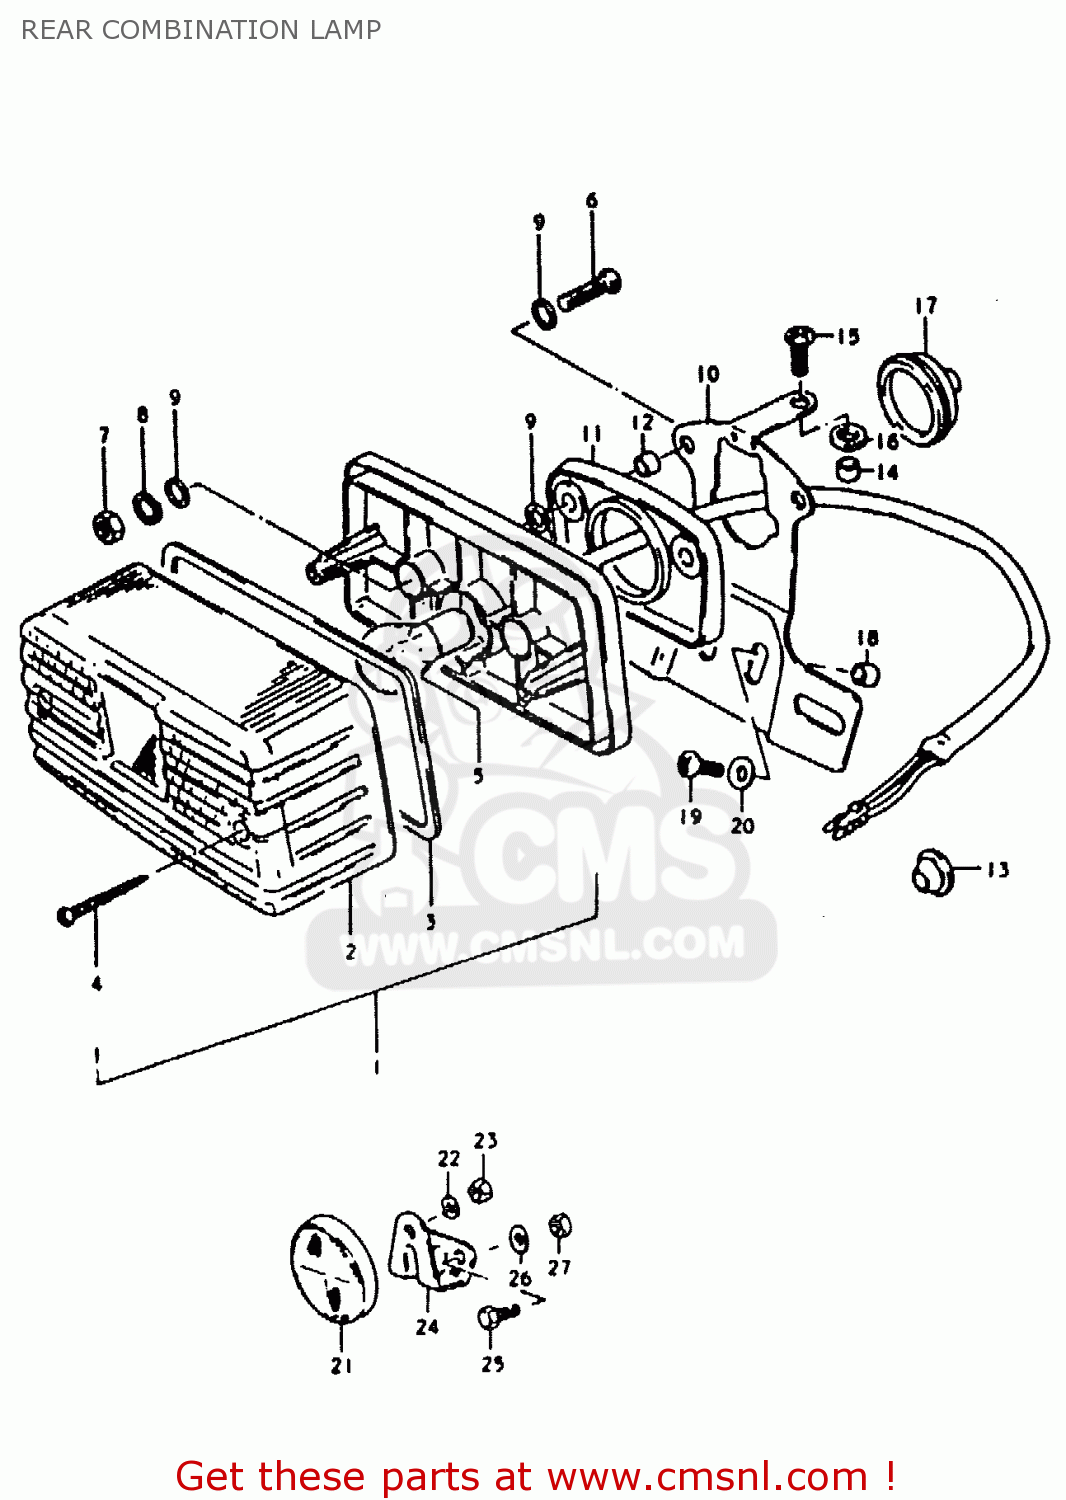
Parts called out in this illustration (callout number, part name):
1	LAMP UNIT, REAR COMBINATION
2	LENS
3	GASKET (NAS)
4	SCREW
5	BULB (6V,21/5W)
6	SCREW
7	NUT
8	LOCK WASHER
9	WASHER
10	BRACKET ASSY
11	CUSHION
12	SPACER
13	GROMMET
14	SPACER (6.1X8X5.2)
15	SCREW (6X15)
16	CUSHION
17	GROMMET
18	SPACER (6.3X9.1X6.7)
19	SCREW
20	WASHER
21	REFLECTOR,REFLEX
22	LOCK WASHER
23	NUT
24	BRACKET
25	BOLT
26	WASHER
27	NUT
